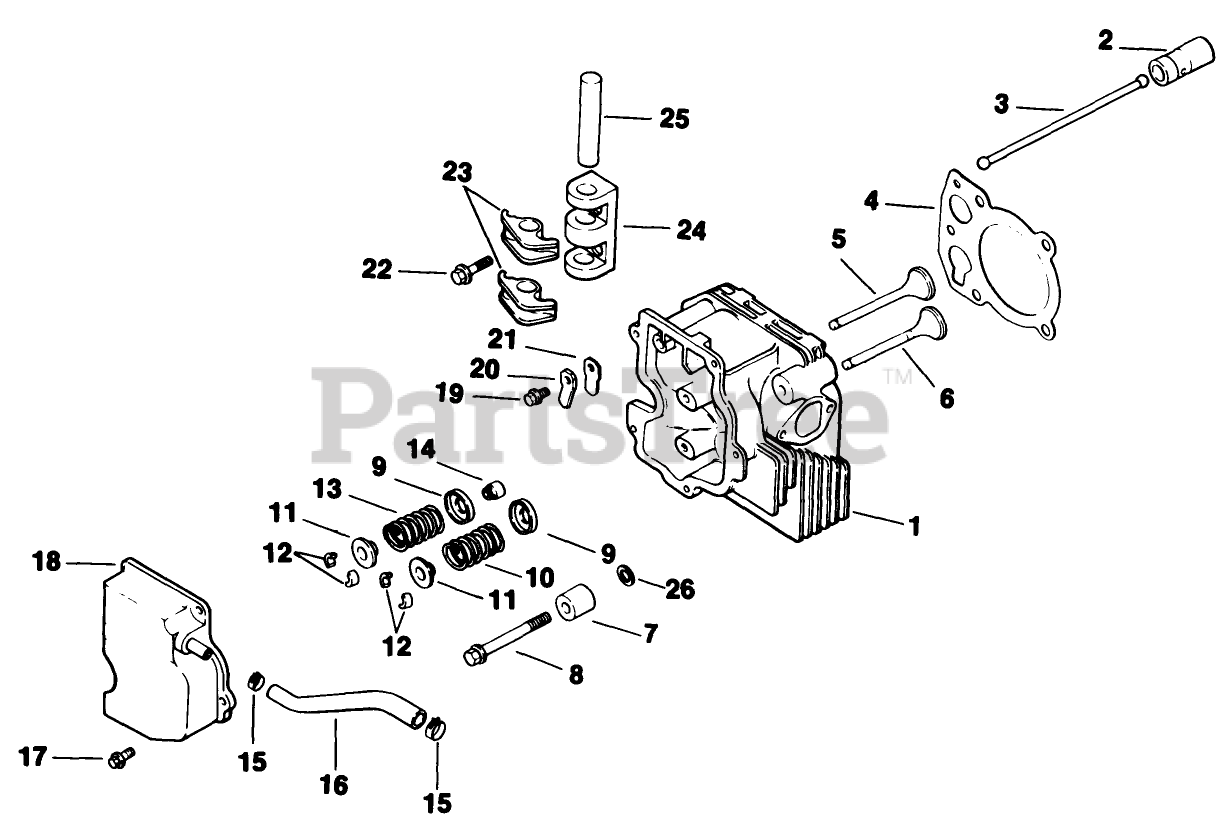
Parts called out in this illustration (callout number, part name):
1	Cylinder Head
2	Lifter-Valve
3	Rod-Push (Only On: 72042,72043,72062,72063)
4	Gasket-Cylinder Head (Only On: 72042, 72063, 72062, 72043)
5	Valve-Intake STD (Only On: 72042, 72063, 72062, 72043)
6	Valve-Exhaust STD (Only On: 72042,72043,72062,72063)
7	Spacer-Head Bolt Exhaust (Only On: 72042, 72063, 72062, 72043)
8	Screw M10x1.5x80 (Only On: 72042, 72063, 72062, 72043)
9	Retainer-Spring
10	Spring-Valve Intake (Only On: 72042, 72063, 72062, 72043)
11	Cap-Valve Spring
12	Kit-Retainer
13	Spring-Valve Exhaust (Only On: 72042,72043,72062,72063)
14	Seal
15	Clamp
16	Hose-Breather (Only On: 72042, 72063, 72062, 72043)
18	Cover-Valve W/Nipple (Only On: 72042, 72063, 72062, 72043)
20	Retainer-Reed
23	Arm-Rocker
24	Bridge-Rocker Arm
25	Shaft-Rocker Arm
26	Washer-Flat (Only On: 72042, 72063, 72062, 72043)
